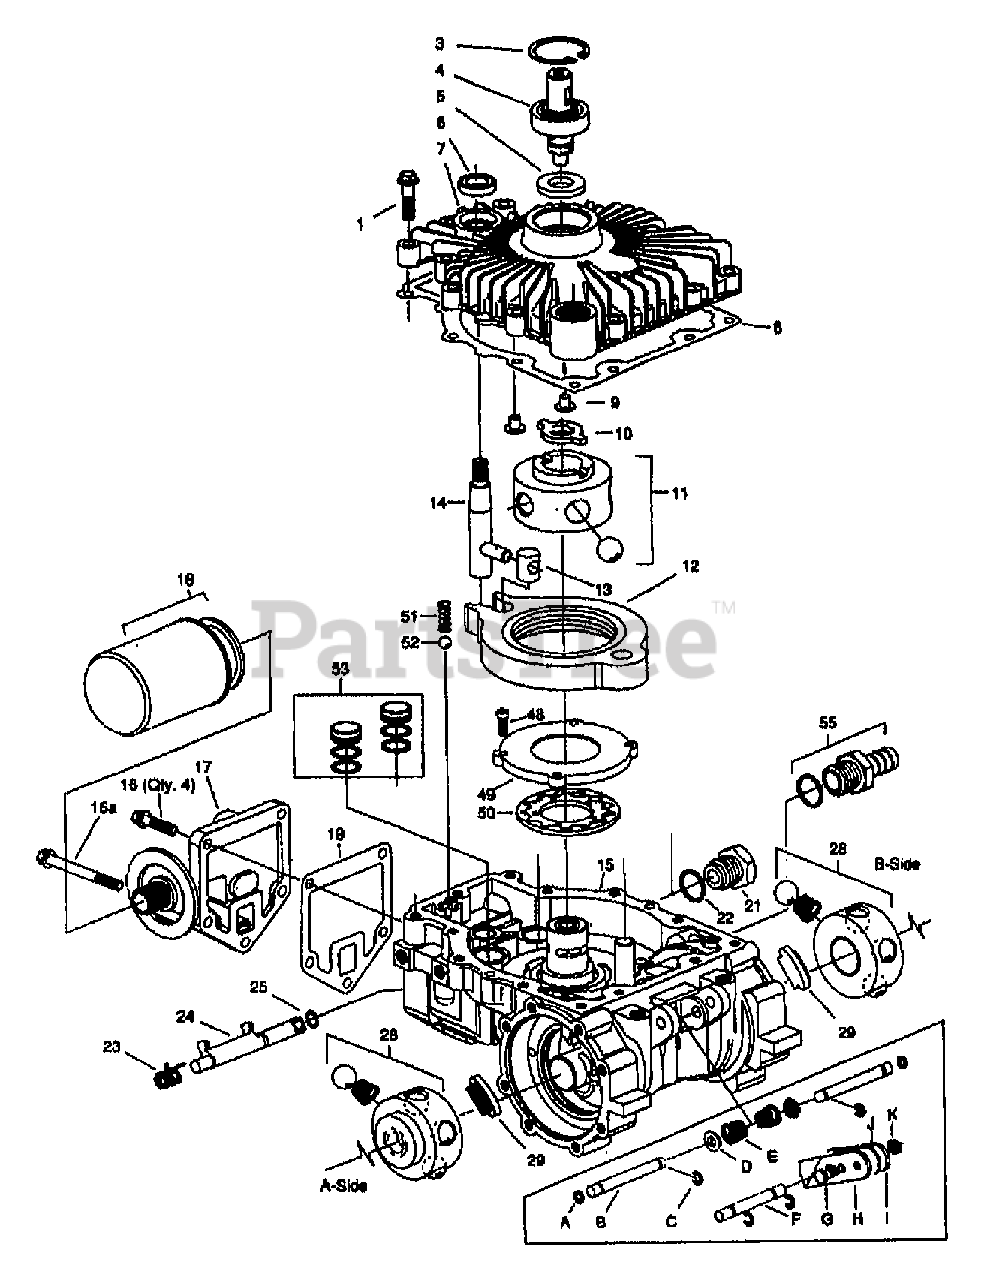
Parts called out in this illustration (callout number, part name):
3	RING-RETAINING
4	SHAFT-INPUT
5	SEAL-OIL
6	SEAL-CONTROL SHAFT
7	COVER
8	COVER-GASKET
9	BUTTON
10	DRIVE
11	PUMP ROTOR/BALL/PN
12	RING-CAM
13	INSERT
14	SHAFT-CONTROL EXT THREAD
15	HOUSING
17	BASE-FILTER
18	FILTER
19	GASKET
22	SEAL-O RING
23	VALVE-SPRING DUMP
24	BRACKET
25	RING-O
28	15T MOTOR ROTOR/BALL
29	PAD-FRICTION
48	SCR-HXSKT
49	PUMP-PLATE
50	GEROTOR
51	SPRING
53	PISTON
55	FITTING-ORING
